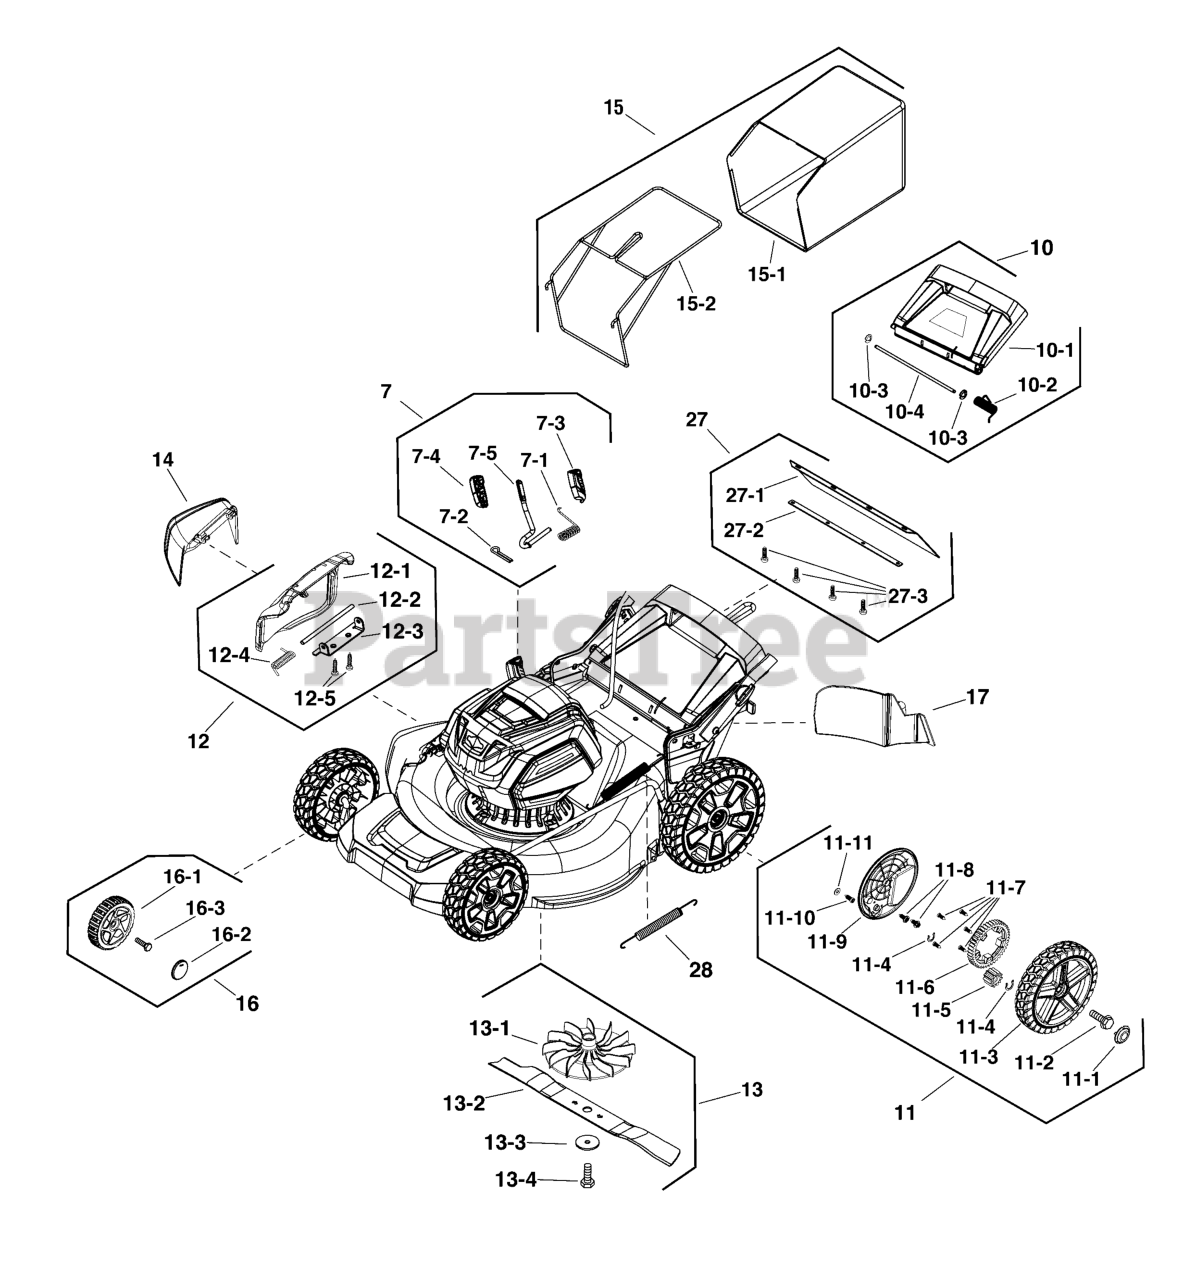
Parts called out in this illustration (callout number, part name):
7	KIT, Height Adjust
7-1	SPRING
7-2	PIN, Cotter
7-3	HOUSING, Left
7-4	HOUSING, Right
7-5	ROD, Adjusting
10	KIT. Rear Cover
10-1	COVER, Rear
10-2	SPRING
10-3	WASHER, Split
10-4	SHAFT
11	KIT, Rear Wheel, 10"
11-1	COVER, Wheel
11-2	BOLT
11-4	RING, Snap
11-5	GEAR, Drive
11-6	GEAR, Drive
11-8	SCREW, HexHead Self Tap
11-9	COVER, Dust
12	KIT, Cover, Side Discharge
12-1	COVER
12-2	SHAFT
12-3	BRACKET
12-4	SPRING, Torsion
13	KIT, Mower Blade
13-1	FAN
13-2	BLADE, Mower
13-3	WASHER
14	KIT, Deflector, Side Discharge
15	GRASS CATCHER ASSEMBLY
15-1	BAG, Grass Catcher
15-2	FRAME
16	KIT, Front Wheel, 8"
16-2	COVER, Wheel
16-3	BOLT
17	PLUG, Mulching
27	KIT, Rear Deflector
27-1	FLAP, Rear
27-2	BRACE
28	SPRING, Tension, Lift
